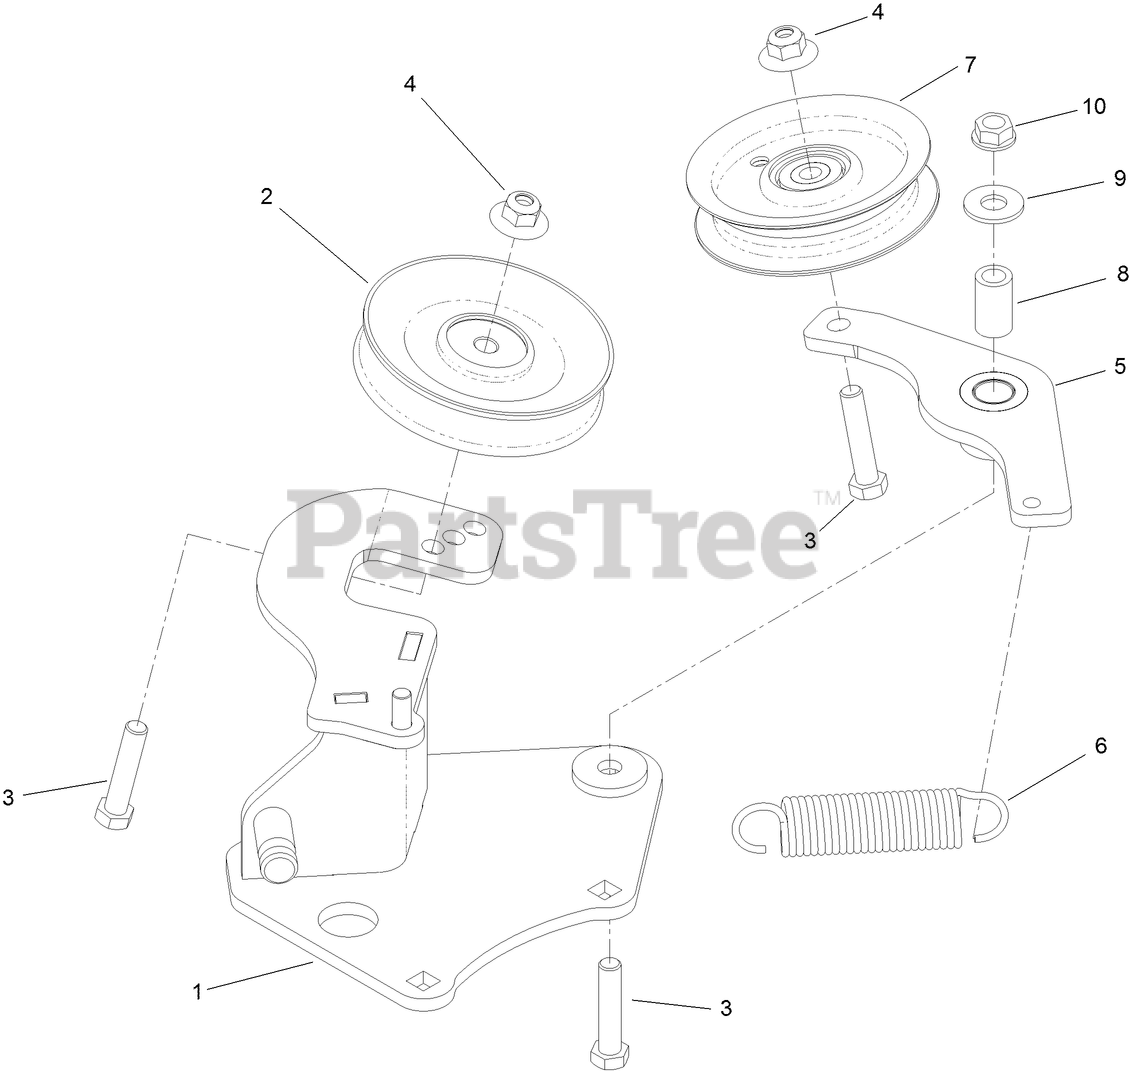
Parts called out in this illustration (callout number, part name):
1	BRACKET-IDLER
2	PULLEY-IDLER
3	SCREW-HH
4	NUT-FLANGE, NI
5	IDLER ASM
6	SPRING-EXTENSION
7	PULLEY-IDLER, FLAT
8	BUSHING-PIVOT, IDLER
9	WASHER-FLAT
10	NUT-HHF, WHIZ
